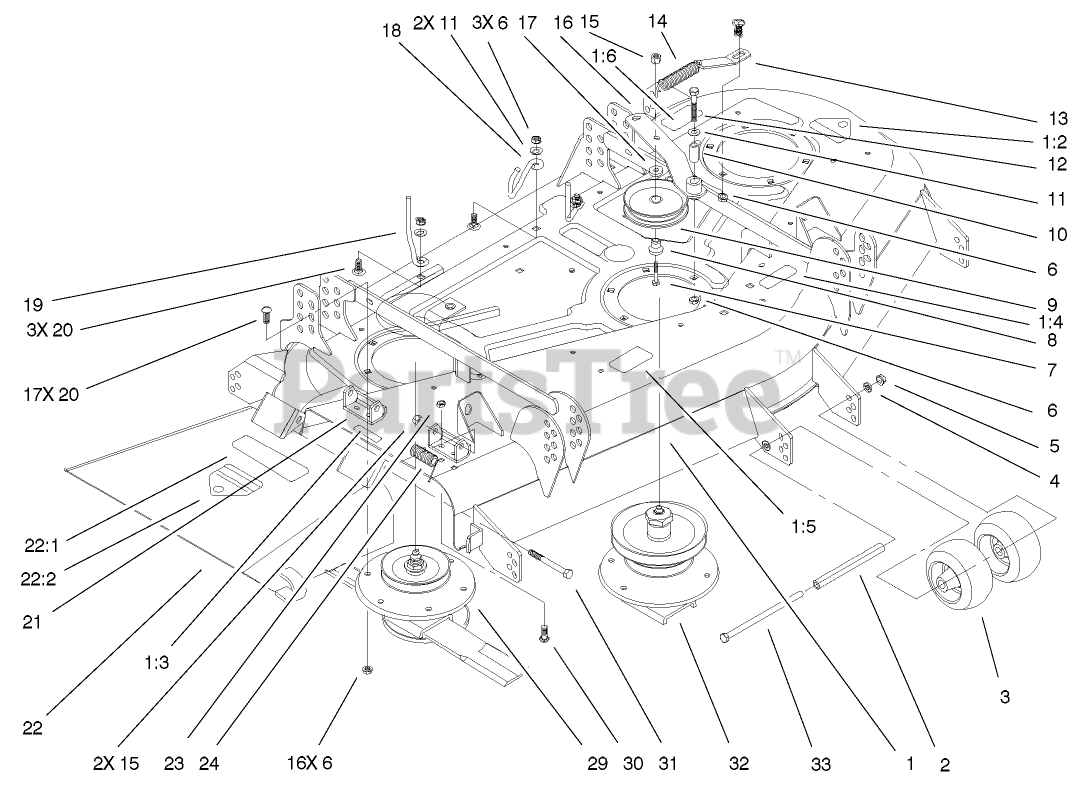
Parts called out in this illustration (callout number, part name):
1	52" DECK W/DECALS
1:2	DECAL-DANGER
1:3	DECAL-DANGER
1:4	DECAL-DANGER
1:5	DECAL-DANGER, THROWN OBJECT
1:6	DECAL-TORQUE
2	SPACER-WHEEL
3	WHEEL-GAGE
4	WASHER-PLAIN
5	NUT-LOCK, NI
6	NUT-HF
7	SCREW-HH
8	BUSHING-PULLEY
9	PULLEY-IDLER
10	SLEEVE
11	WASHER-FLAT
12	SCREW-HH
13	PLATE-SPRING
14	SPRING-EXTENSION
15	NUT-HEX
16	IDLER ARM ASM
17	WASHER-FLAT
18	GUIDE-BELT
19	ROD-BELT
20	SCREW-CARR
21	BRACKET-PIVOT
22	Deflector ASM
22:1	DECAL-DANGER
22:2	DECAL-DANGER
23	NUT-LOCK, CONE
24	SPRING
29	SPINDLE AND BLADE ASM
30	SCREW-CARR
31	SCREW-HH
32	CENTER SPINDLE AND BLADE ASM
33	SCREW-HH
